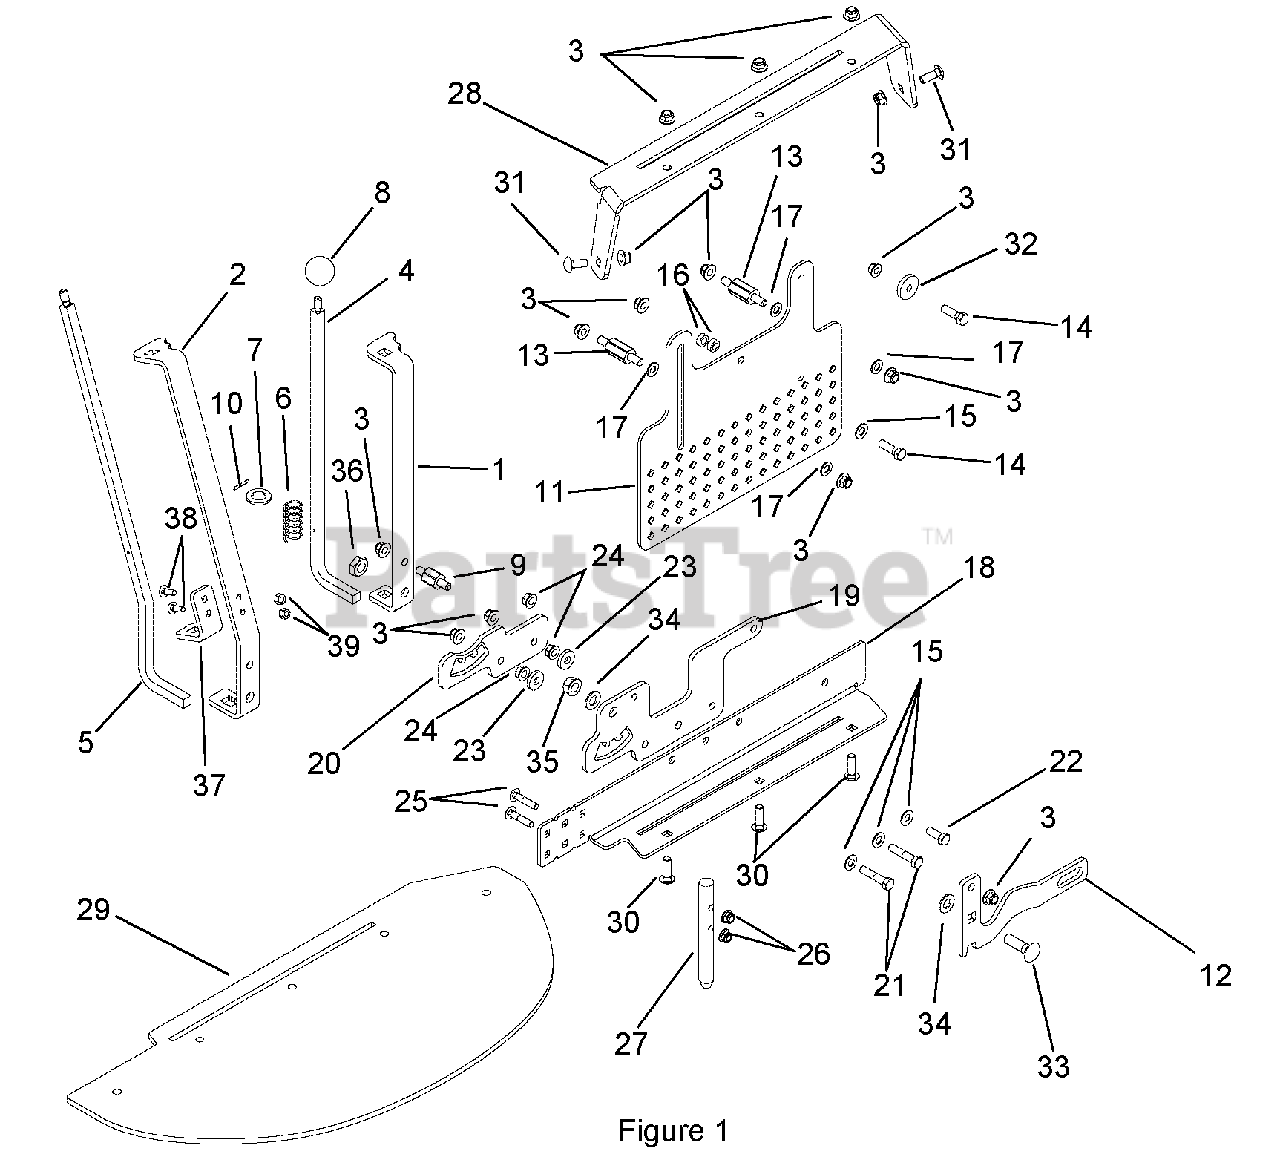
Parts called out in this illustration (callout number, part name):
1	Plate Control Lever (79210300)
2	Plate Control Lever (79210500)
3	3/8-16 Nyloc Flange Nut
4	Plate Control Rod (79210300)
5	Plate Control Rod (79210500)
6	Compression Spring
7	3/4 x 1-1/4 Flat Washer
8	Black Ball Knob
9	Lever Tie Lifter Pin
10	1/8 x 1.00 Roll Pin
11	Block-off Baffle Plate (79210300)
12	Block-off Lifter Cam Bracket
13	Plate Stabilizer Pin
14	3/8-16 x 1-1/4 Hex Bolt
15	3/8 x 13/16 Flat Washer
16	Sleeve Bushing
17	3/8 x 3/4 Nylon Flat Washer
18	Chute Mount Bracket (79210300)
19	Chute Control Master Plate
20	Chute Control Backup Plate
21	3/8-16 x 1-3/4 Hex Bolt
22	3/8-16 x 1 Hex Bolt
23	13/32 x 1 Flat Washer
24	3/8-16 Spinlock Flange Nut
25	5/16-18 x 1-1/2 Round Head Square Neck Bolt
26	5/16-18 Nyloc Flange Nut
27	Discharge Chute Pin
28	Chute Support Bracket (79210300)
29	Rubber Chute (79210300)
30	3/8-16 x 1-1/4 Round Head Square Neck Bolt
31	3/8-16 x 1 Round Head Square Neck Bolt
32	3/8 x 1-1/2 Flat Washer
33	1/2-13 x 1-3/4 Round Head Square Neck Bolt
34	1/2 x 1.00 Nylon Flat Washer
35	1/2-13 Locking Top Flange Nut
36	1/2-13 Thin Locking Nyloc Nut
37	Rod Lever Control Support Bracket (79210500)
38	1/4-20 x 3/4 Round Head Square Neck Bolt (79210500)
39	1/4-20 Locking Center Nut (79210500)
